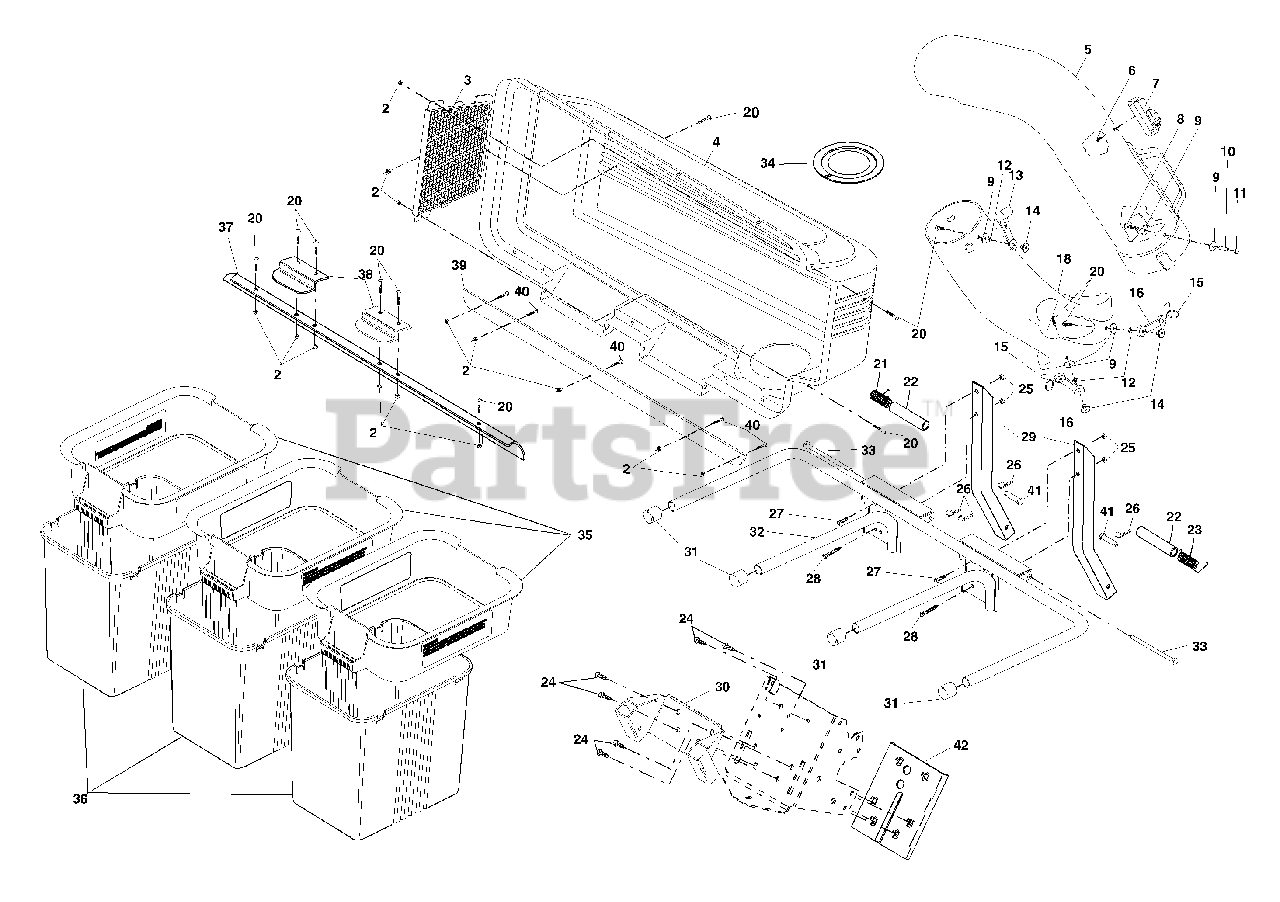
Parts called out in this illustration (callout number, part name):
2	Nut, Crownlock #10-24
3	Screen, Cover
4	Cover
6	Screw, Special #10-14x1/2
7	Dump Bagger Indicator
8	Screw, #10-24 x 1-1/8
9	Washer 3/16x3/4x16 Ga.
10	Spacer, Split
11	Nut, Acorn #10-24
14	Nut, Weld
15	Latch, Hook
16	Rubber, Latch
20	Screw #10-24 x 5/8
21	Spring, Cover L.H. (black)
22	Spacer, Cover
23	Spring, Cover R.H. (gray)
24	Bolt, 7/16-14 x 3/4
25	Locknut 5/16 x 18
26	Spring, Retainer
27	Bolt, Hex 5/16-18 x 3/4
28	Bolt, Hex 5/16-18 x 2-1/4
29	Bagger, Support Post
30	Bracket, Mounting
31	Plug, Tubing End
32	Bagger, Frame
33	Pin, Hinge
34	Gasket, Cover
35	Container, Top
36	Container, Bottom
38	Latch Handle, Cover
39	Strip, Reinforcement
40	Screw #10-24 x 1/2
42	Plate, Reinforcement
